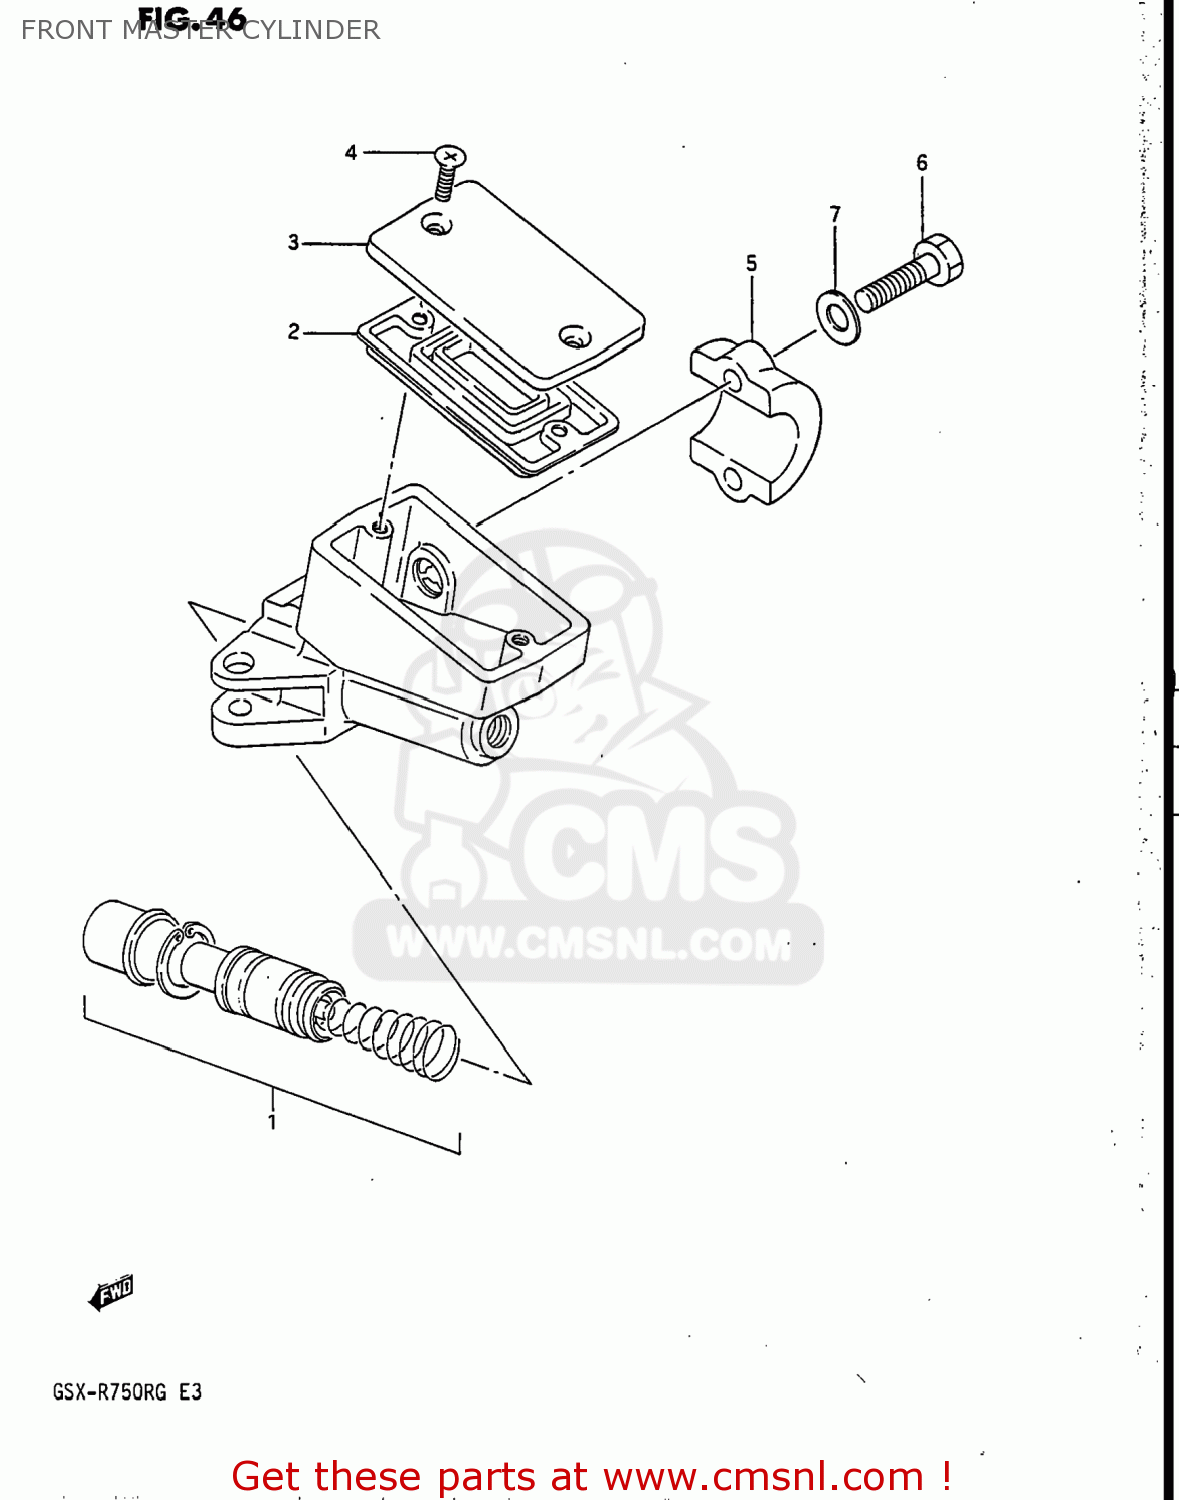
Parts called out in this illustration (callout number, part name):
1	PISTON & CUP SET
2	3
3	CAP
4	SCREW
5	HOLDER,MASTER CYLINDER
6	BOLT
7	WASHER
